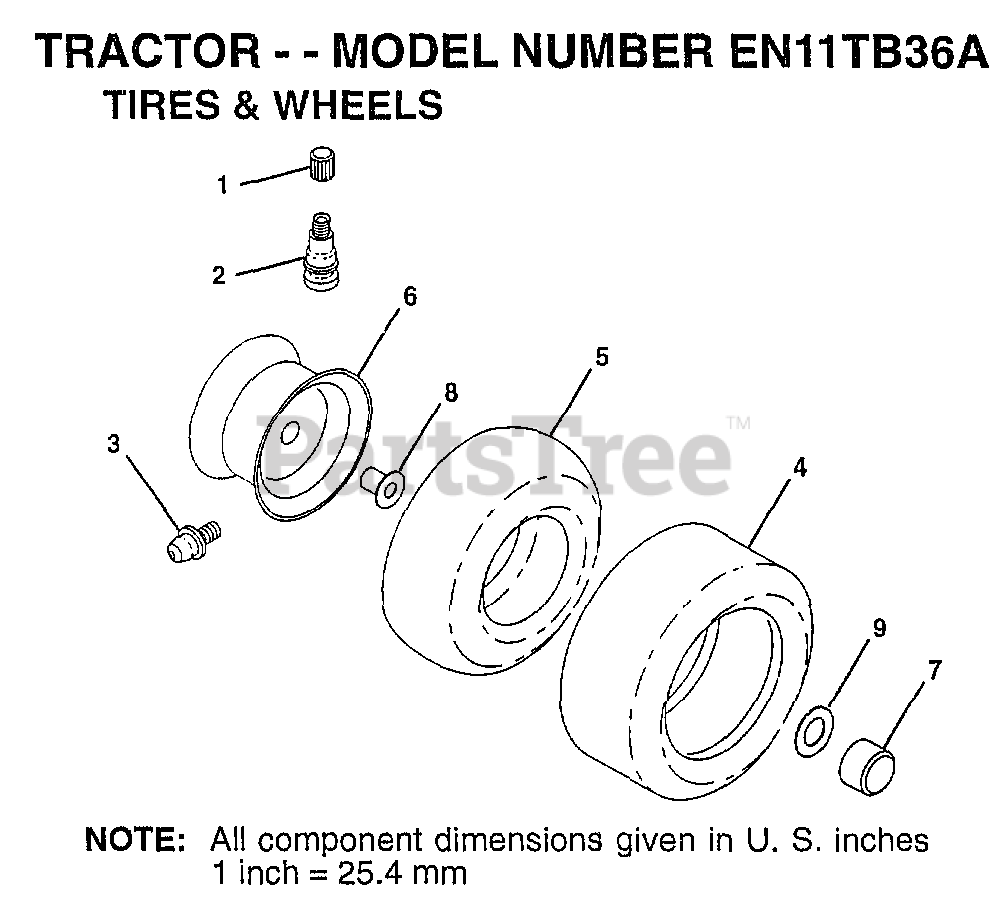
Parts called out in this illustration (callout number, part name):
1	VALVE CAP
2	VALVE STEM LT
3	FITTING LT
5	TUBE.5.3/4.5/6
5	TUBE.16X6.5/7.5-8
6	"RIM 6"" FRONT 421"
6	"RIM REAR 8"""
7	HUB CAP
8	"FLANGE, BEARING"
9	WASHER
